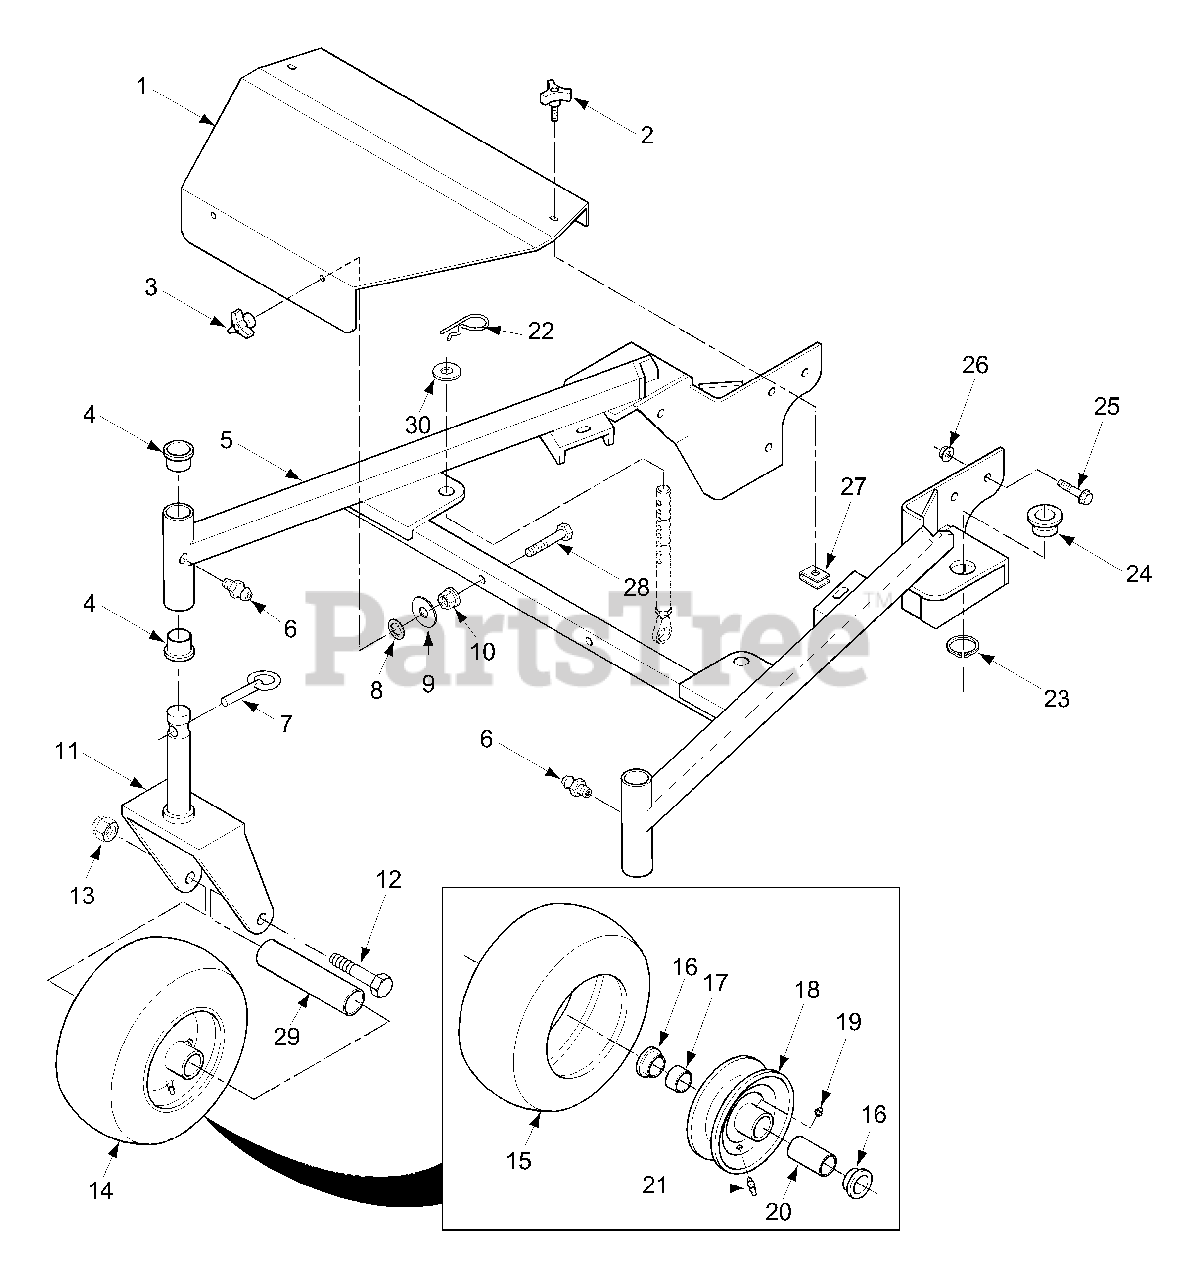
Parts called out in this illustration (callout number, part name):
1	Belt Cover With Decal - 48"
1	Belt Cover With Decal - 52"
2	Knob With Stud
3	Knob, Deck Cover Mounting
4	Bushing, Caster
5	Frame Weldment, Deck Mounting - 48"
5	Frame Weldment, Deck Mounting - 52"
6	Grease Fitting Str. 1/4-28 Self Tap
7	Quick Pin,.438 Dia
8	Nut, Push-On - 3/8 Thd.
9	Flatwasher, 3/8 (.391 x .938 x .105)
10	Nut, 3/8-16 Serrated Flange Hex Head
11	Yoke, Caster Wheel
12	Capscrew, Hex Head 1/2-13 x 6.50"
13	Locknut, 1/2-13 Elastic Stop
14	Wheel Assembly, Caster
15	Tire, 11 x 4.00-5
16	Retainer
17	Roller Bearing
18	Rim, 5.0 x 2.75 With Zerk & Valve
19	Grease Fitting Str.1/4-28
20	Roler Bearing .625 x 3.25"
21	Tire Valve
22	Hair Pin Cotter, .177 x 3.25"
23	Retaining Ring 1.50 Ext.
24	Bushing, Deck Adjustment Pin
25	Capscrew, Hex Head 7/16-14 x 1.0"
26	Nut, 7/16-14 Serrated Flange Hex
27	U-Nut, 3/8-16
28	Capscrew, Hex Head 3/8-16 x 2.25"
29	Sleeve, Caster Wheel
30	Flatwasher, 5/8 - (.688 x 1.75 x .134)
